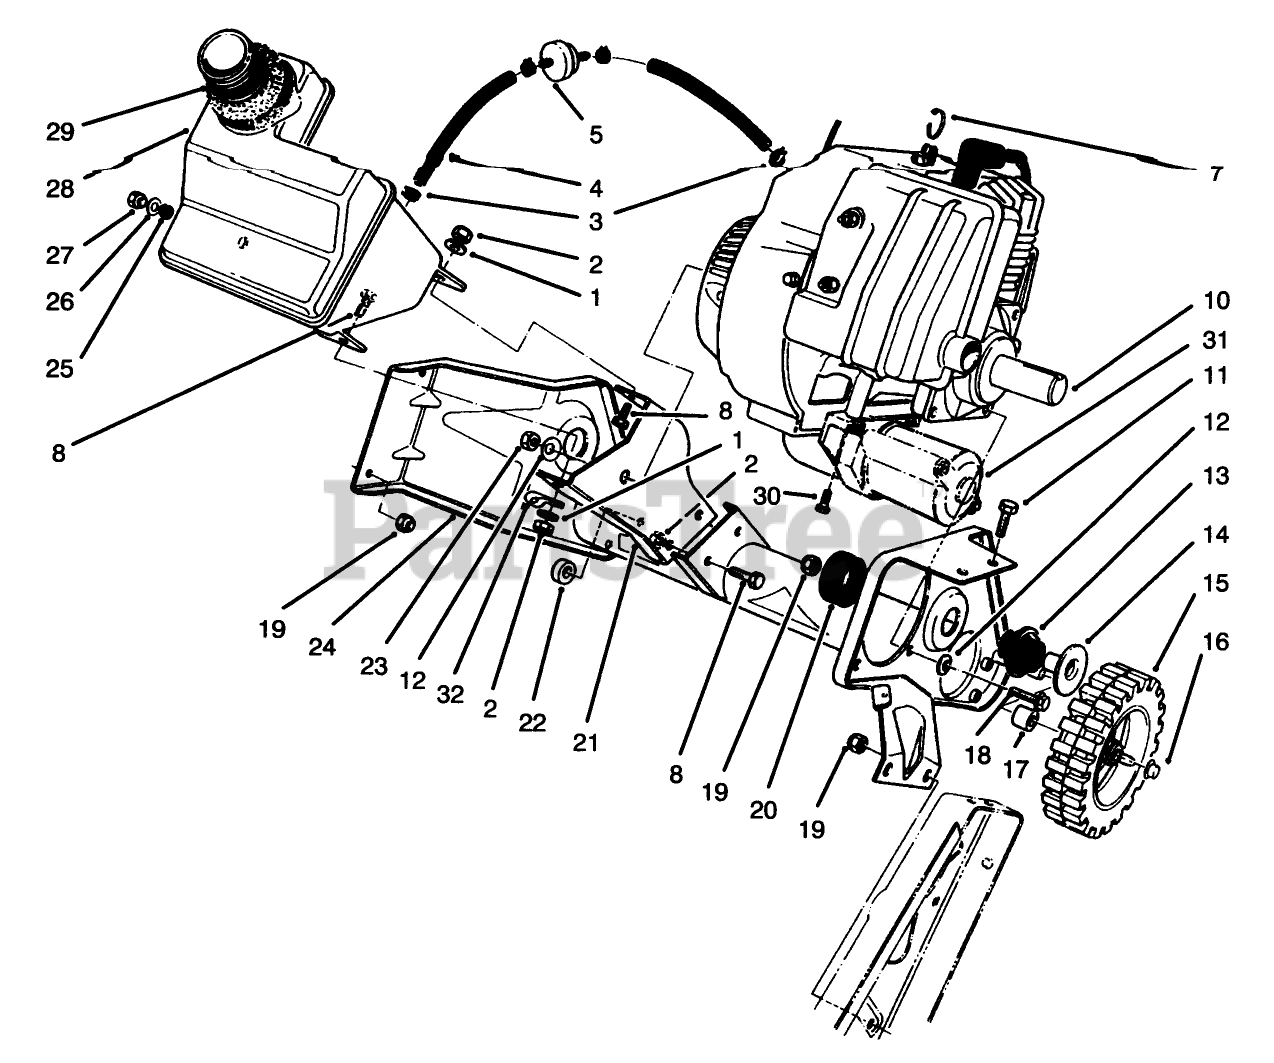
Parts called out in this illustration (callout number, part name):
1	WASHER-FLAT
2	NUT-LOCK, NI
3	CLAMP-HOSE
4	GAS LINE
5	FILTER-FUEL
7	TIE-CABLE
8	SCREW-HH
11	SCREW-HH
12	WASHER-BELLEVILLE
14	SPACER TUBE
15	WHEEL
16	NUT-PUSH
17	SPACER-WHEEL
19	NUT-LOCK, NI
20	LOAD MOUNT
22	SPACER-WHEEL
25	GROMMET-RUBBER
26	WASHER-PLAIN
27	NUT-LOCK, CONE
29	SEAL-FOAM
32	CLAMP
